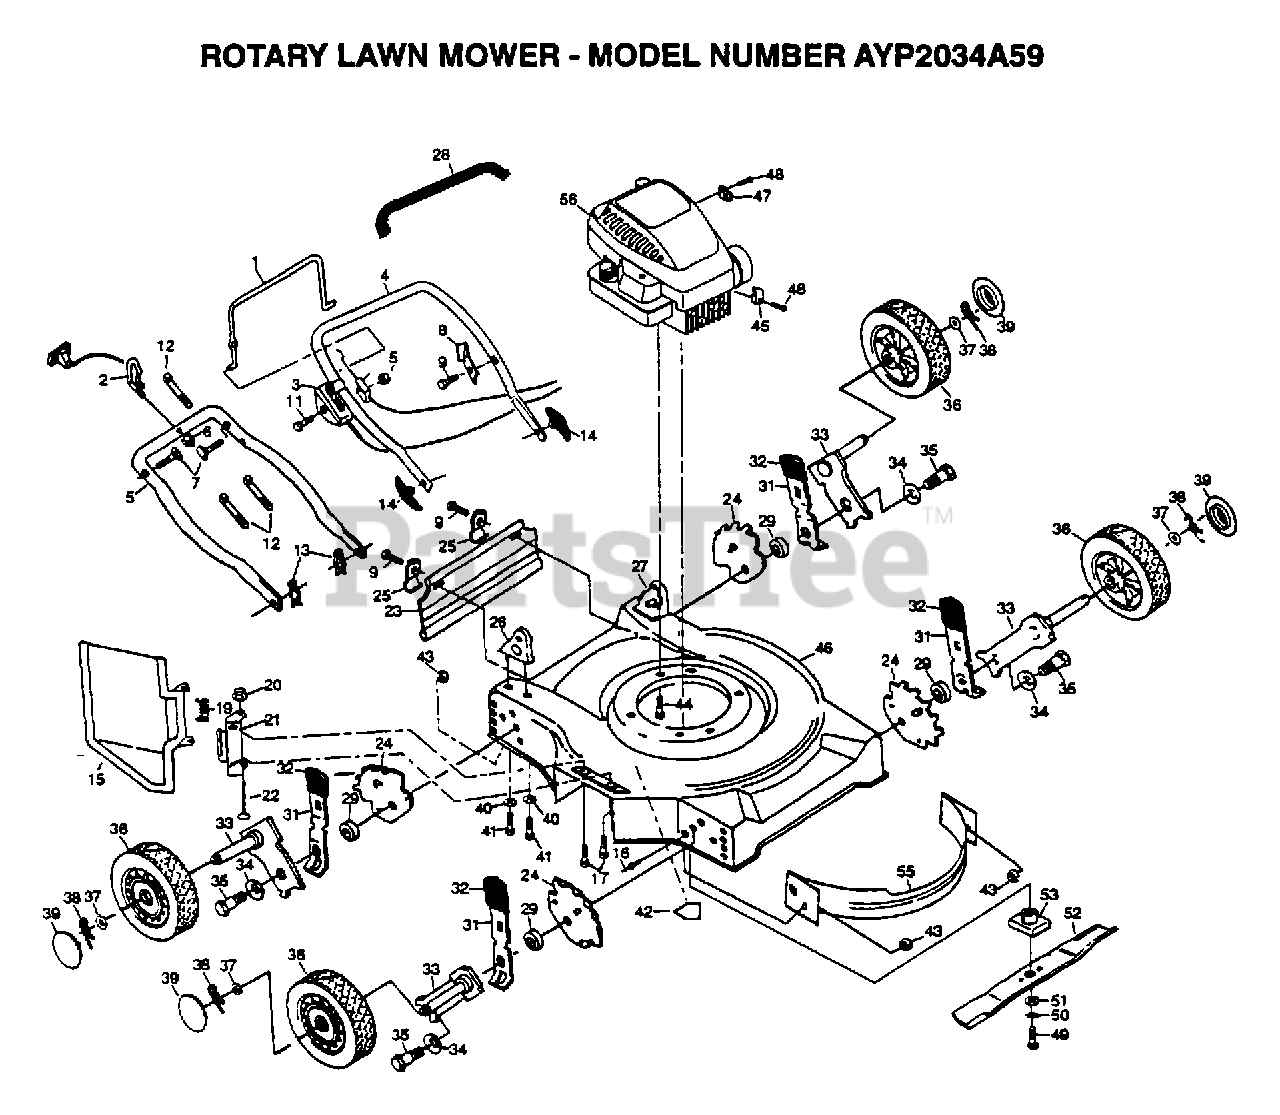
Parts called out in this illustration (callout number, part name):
1	CONTROL BAR PM
2	ROPER GUIDE PM
3	"CONTROL, THROTTLE"
7	BOLT.HANDLE.LM
8	"BRKT,UPSTOP"
9	TAPPING SCREW
10	"CABLE,ENG ZONE CO"
11	SCREW.HXHD.WASH.
13	HAIRPIN COTTER
14	KNOB HANDLE
15	"GRD,DISCHARGE"
16	BLIND RIVET
17	SCREW
19	"SPRING,TORSION"
20	PUSH ON SPEED NUT
21	"BRKT,HSG "
23	SKIRT.RD.20/22
24	BRACKET.ADJ.9POS.
25	"BRKT,DEFL PM"
31	SPRING SELECTOR
32	KNOB PM
33	AXLE ARM
34	"WASHER, BELLEVIL."
35	BOLT SHLD 3/8-16
37	WASHER
38	RETAINER CLIP PM
39	HUB CAP
40	STEEL WASHER
41	SCREW
42	DECAL-DANGER PM
43	LOCKNUT PM
44	SCREW
45	CABLE CLAMP
46	"KIT HSG 20"" SD"
47	GUIDE CLIP PM
48	SCREW PM
49	SCREW
50	LOCKWASHER
51	"WASHER,HARDEN"
52	BLADE.STAND.20INC
53	BLADE ADAPTOR
